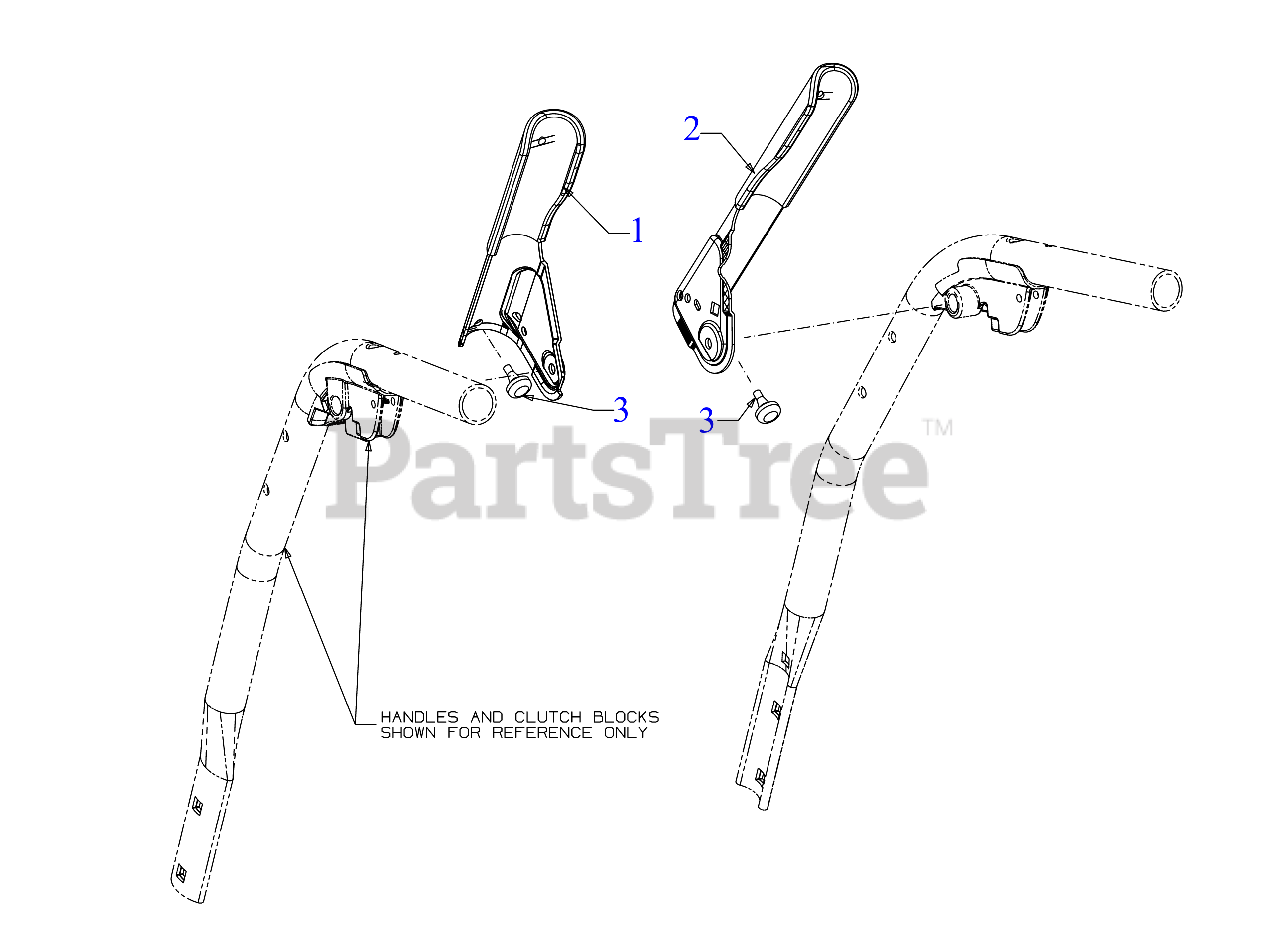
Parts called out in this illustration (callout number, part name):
1	HANDLE ASSEMBLY (LH)
2	HANDLE ASSEMBLY (RH)
3	RUBBER BUMPER
